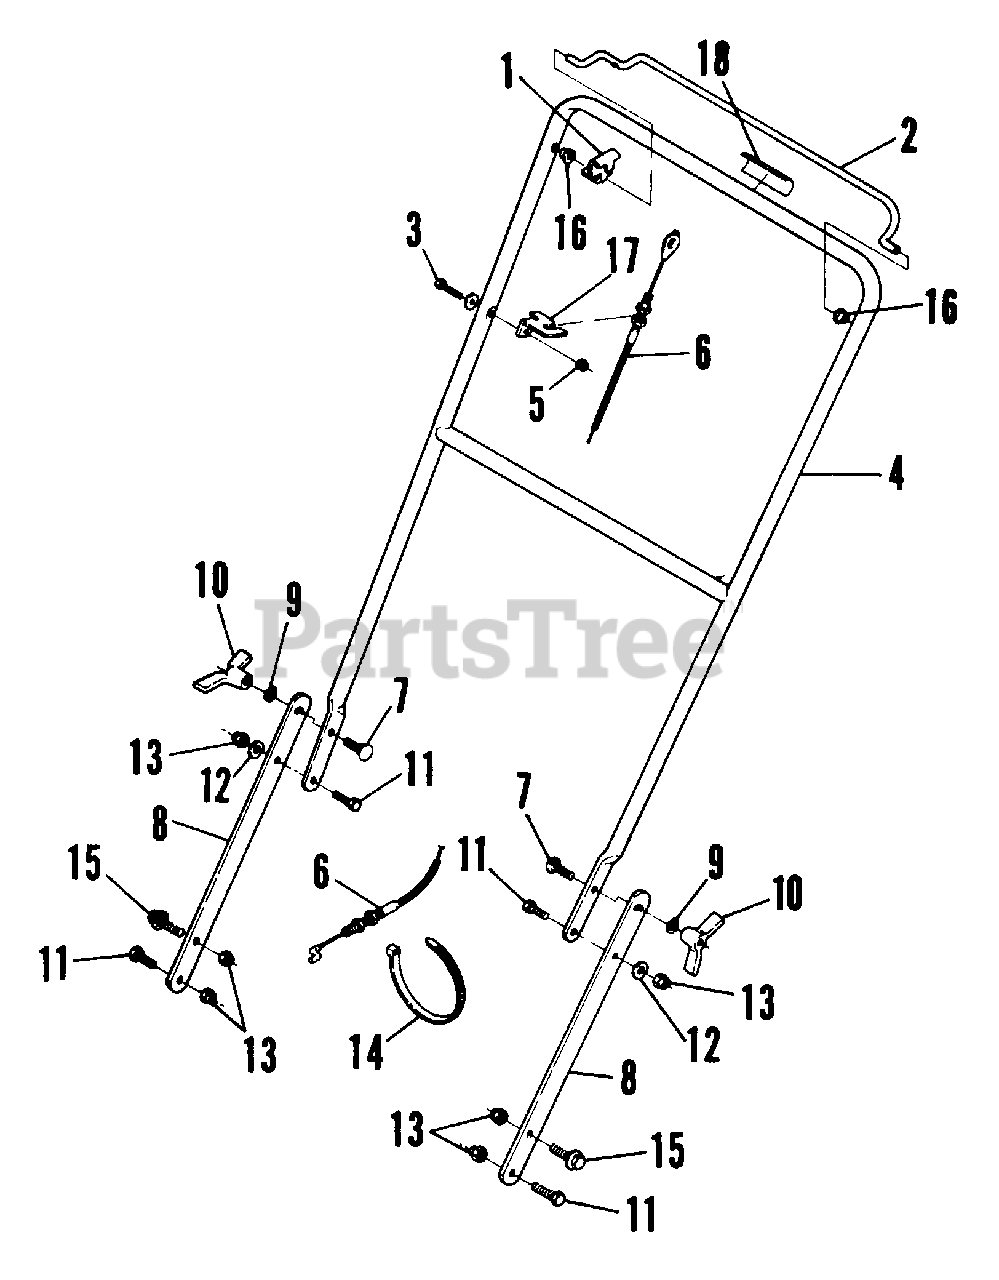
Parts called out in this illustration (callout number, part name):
1	BAIL CATCH
2	BAIL
3	CAPSCREW, 1/4" - 20 x 1 1/2"
4	UPPER HANDLE
5	NYLOC HEX. NUT, 1/4" - 20
6	CLUTCH CABLE
7	CARRIAGE BOLT, 5/16" - 18 x 1"
8	LOWER HANDLE
9	LOCKWASHER, 5/16"
11	CAPSCREW GR. 5, 3/8" - 16 x 1" Hex. Hd.
12	FLAT WASHER, 3/8" Std.
13	NYLOC HEX. NUT, 3/8" - 16
14	PLASTIC TIE, 1/8" - 6"
15	CAPSCREW GR. 5, 3/8" - 16 x 1 1/4" Hex. Hd.
16	BUSHING
17	CABLE MOUNT
